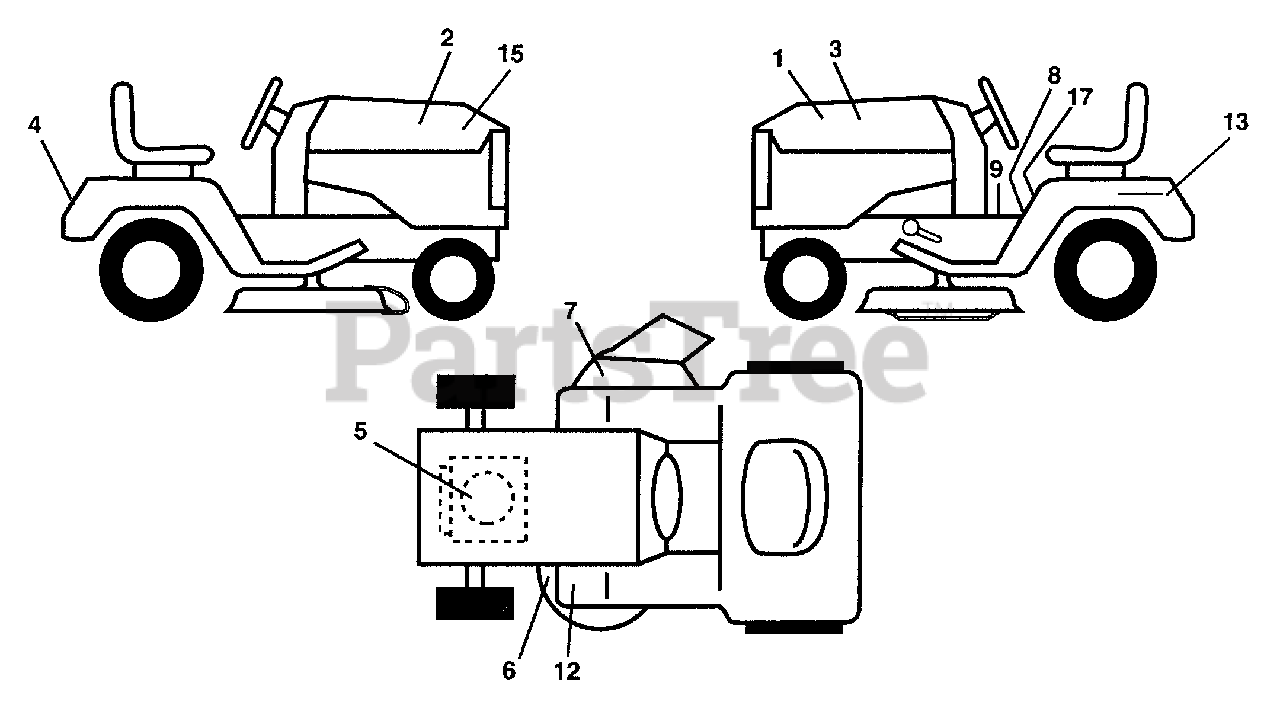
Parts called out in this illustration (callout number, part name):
1	Decal Hood Slope LH
2	Decal Hood Slope RH
3	Decal Panel Side LH
4	Decal Fender
5	Decal Engine 12.5 HP B&S ICQ
6	Decal, V-Belt Sch 38"/42" LT
7	Decal Warning MULT-LANGUAGE
8	Decal Dash Instructions Operating Eng/Fr
9	Decal Sdl Cold Start Hydo Eng/Fr
12	Decal Clutch/brake Eng/Fr/Ger/Du
13	Decal Caution Battery Fr/Ger
15	Decal Panel Side RH Hydr.
17	Decal Caution Fender Eng/Fr
